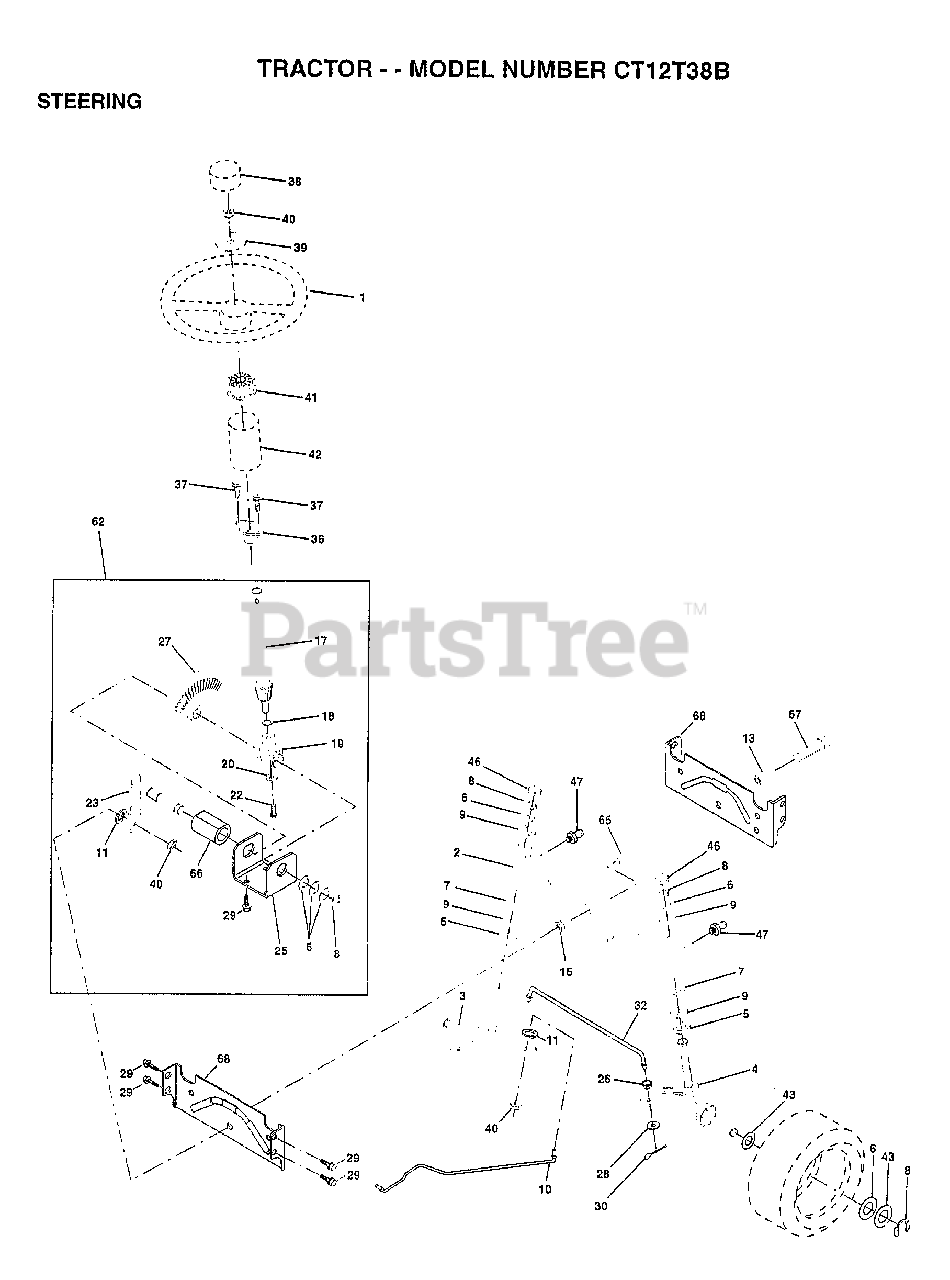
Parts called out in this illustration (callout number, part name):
2	AXLE ASM
3	SPINDLE.ASM.LH
4	"SPINDLE ASM,RH"
5	WASHER .T
6	WASHER
7	WASHER
8	RING
9	COL. SRTG. BEAR.
10	DRAGLINK-STAMPED
11	LOCKWASHER
13	BEARING AXLE
15	"NUT-LOC,FLANGE LT"
17	SHAFT ASSM STEERN
18	THRUST WASHER
19	SUPPORT.SHAFT
22	SCREW HEX SOC1/4-
25	BRKT-STEERING
26	BUSHING.DRAGLINK
27	GEAR SECTOR
28	WASHER
29	SCREW
30	COTTER PIN
32	TIE ROD
36	BUSHING.STEERING
37	"SCREW-TT,10-32 FL"
38	ST WHL INSERT CAP
39	WASHER T
40	GRIPCO NUT
41	ADAPTER-WHEEL LT
42	"TUBE, STR SHAFT"
43	WASHER
46	CAP
47	ZERK M
62	STEERING ASM KIT
65	SPACER AXLE
66	"BEARING-ARM,PITMA"
67	BOLT
68	BRACE AXLE
